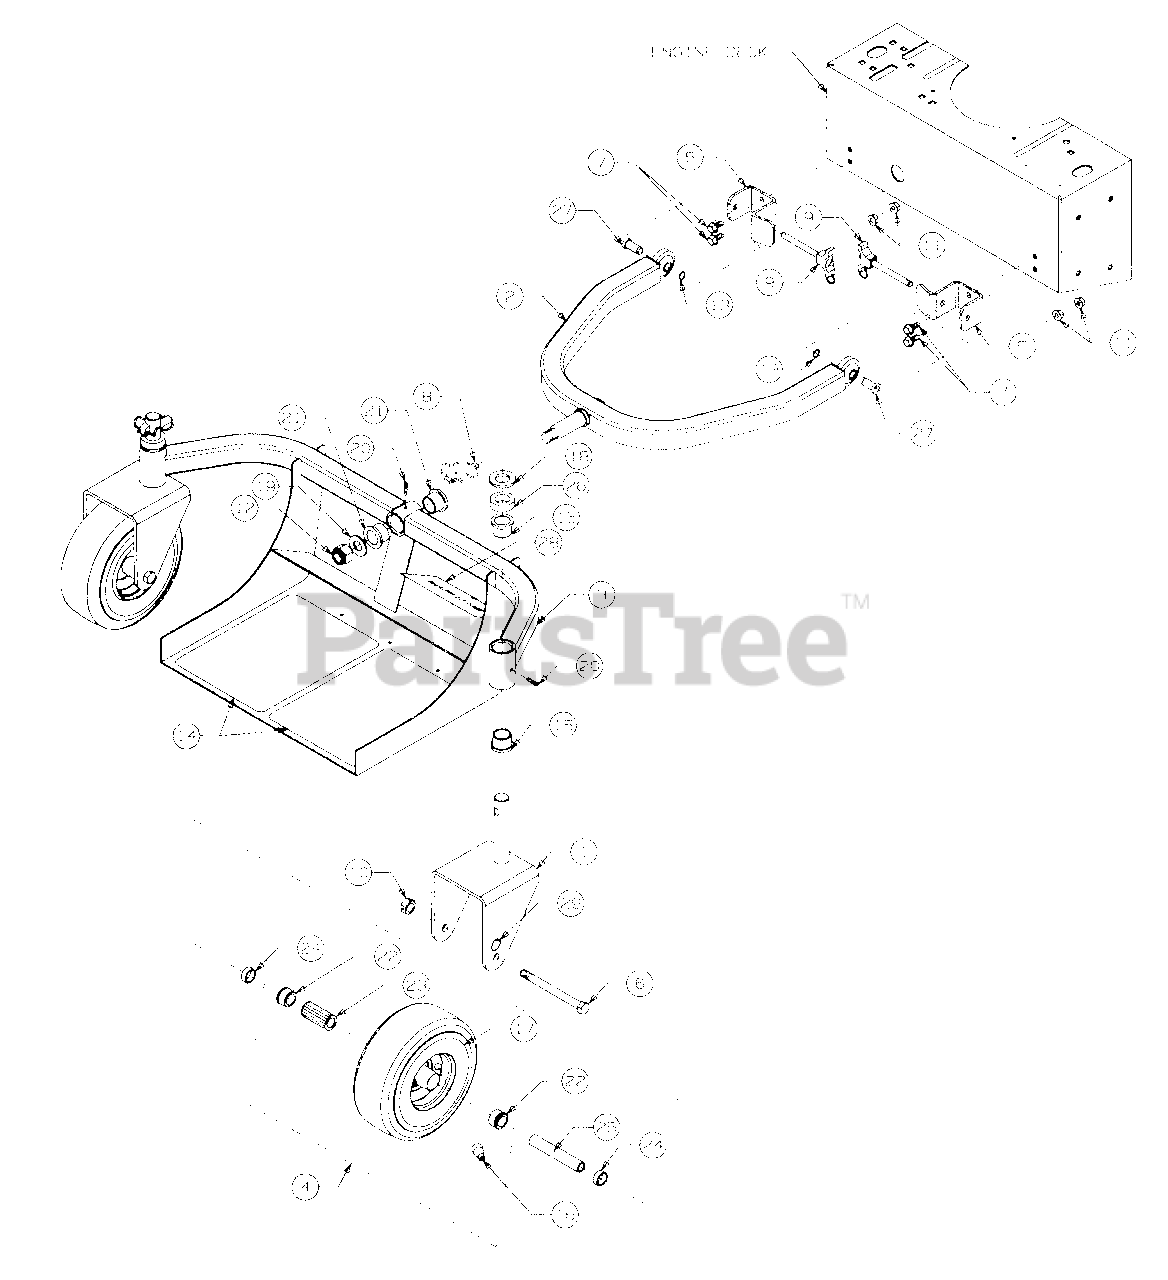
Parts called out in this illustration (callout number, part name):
2	Tubing, A-Frame
7	Screw, Hex Wash Sf Tap, 3/8-16 X .75 Lg
8	Pin, Klik
9	Pin, Quick Release, 3/8 Dia
10	Nut, Hex Center Lock, 1/2-20
11	Nut, Hex Flanged Lock, 3/8-16
12	Nut, Hex Lock, 3/4-16
13	Ring, Retainer
14	Pad, Abrasive Foot
15	Bearing, Flange
16	Valve, Tubeless Air
17	Tire, Smooth, 9.0 X 3.50 X 4
18	Washer, Special
19	Washer, Flat, .750 X 1.50 X .120 Thk
20	Fitting, Lube
21	Bearing, Flange
22	Bearing, Graf Oil Flange
23	Bearing, Roller
24	Spacer, .790 ID X 1.0 OD X .347
25	Spacer, Wheel
26	Spacer, 1.015 ID X 1.62OD X .50 Lg
27	Spacer, Shoulder, .378 ID X .50 OD
28	Graphic, Warning
29	Label Inflation
